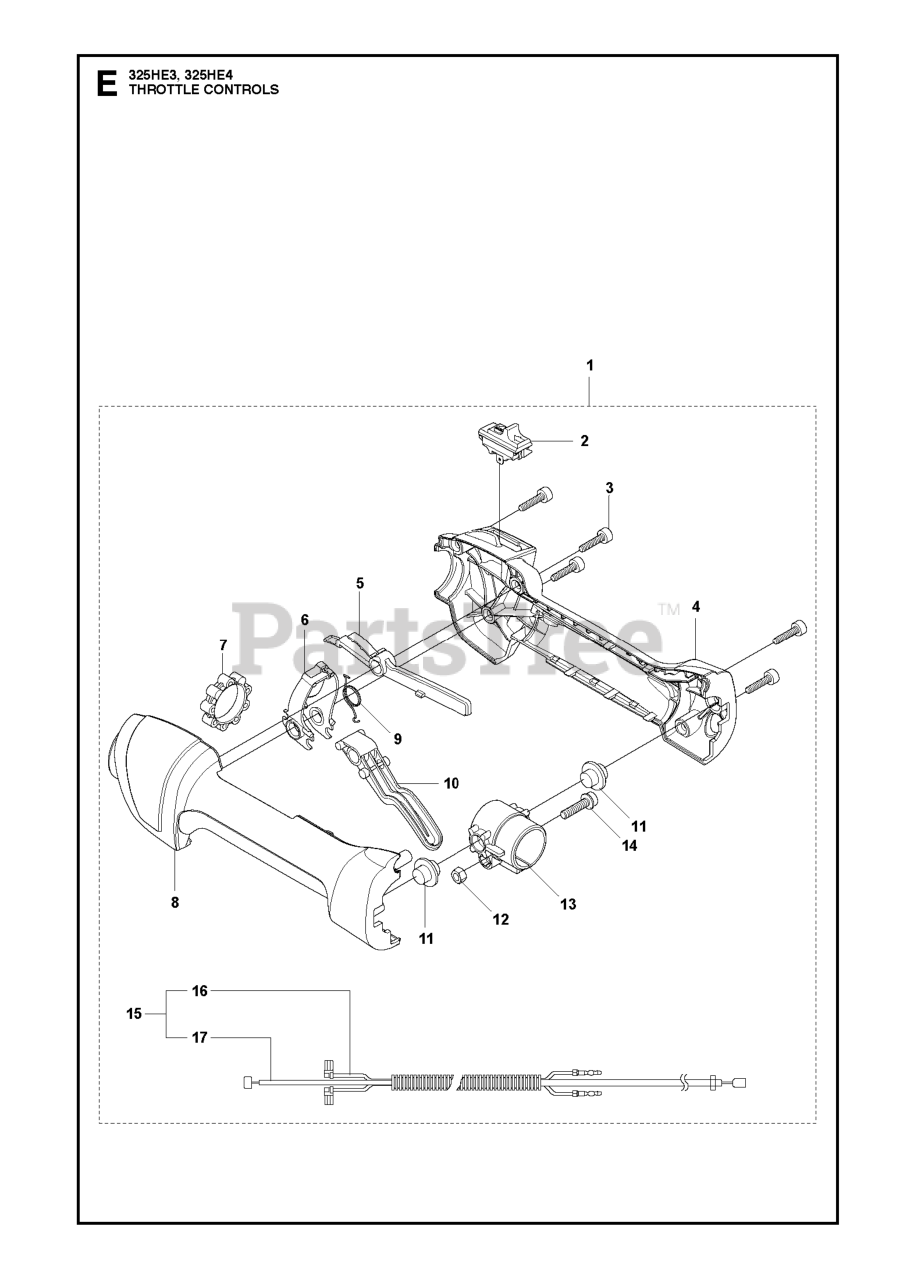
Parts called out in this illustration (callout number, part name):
1	THROTTLE CONTROL ASSY
1	THROTTLE CONTROL
2	STOP BUTTON
4	HANDLE
5	THROTTLE LOCK
7	VIBRATION DAMPER
8	HANDLE
9	RETURN SPRING
10	THROTTLE TRIGGER
11	VIBRATION ABSORBER
15	WIRING ASSY
16	SHORT CIRCUIT CABLE
17	THROTTLE CABLE
